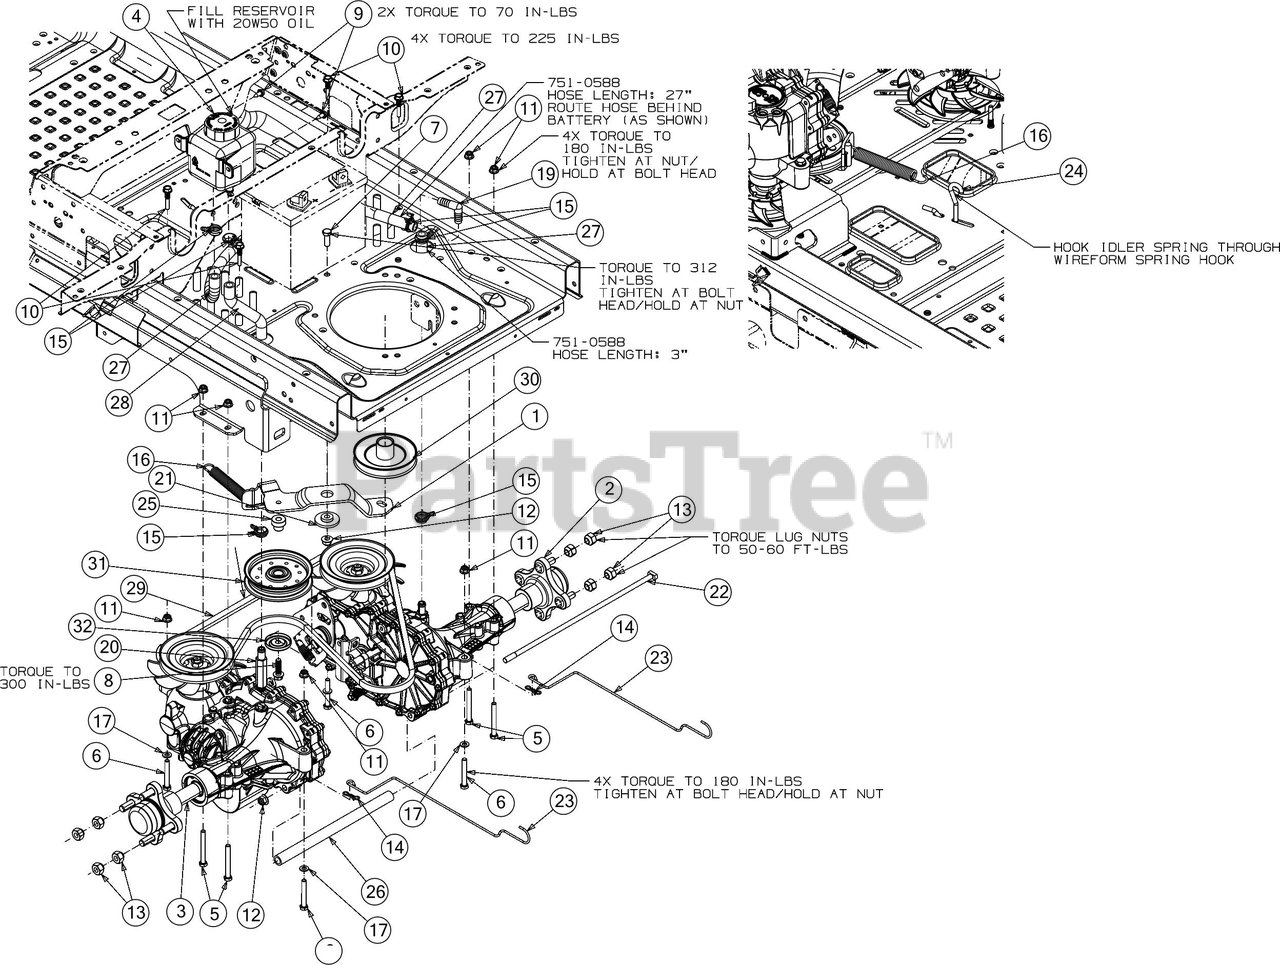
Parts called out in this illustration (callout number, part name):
1	IDLER BRACKET ASSEMBLY
2	HYDRO TRANSMISSION ASSEMBLY (RH)
3	HYDRO TRANSMISSION ASSEMBLY (LH)
4	HYDRAULIC TANK
5	HEX SCREW 5/16-18 x 2.75
6	HEX SCREW 5/16-18 x 2.25 GR5
7	SCREW 3/8-16 x 1 GR5
8	SCREW 3/8-16 X1.250
9	SCREW 1/4-20X.625
10	BELT KEEPER ROD .25 x 1.585
11	FLANGE LOCK NUT 5/16-18
13	LUG NUT 7/16-14
14	BOW TIE COTTER PIN 1/4-5/16
15	FUEL HOSE CLAMP
16	EXTENSION SPRING .75 DIA x 5.87 RZT/F
17	FLAT WASHER
19	90 DEGREE NYLON FITTING
20	EXTENSION FITTING 9/16-18
21	SHOULDER SPACER
22	SUPPORT TUBE ROD
23	HYDRO BYPASS ROD
24	IDLER SPRING HOOK
25	SHOULDER SPACER
26	TRANSMISSION SPACER .75OD x 11.31
27	FUEL LINE 1/2 ID"
28	TRANSMISSION EXPANSION HOSE
29	TRANSMISSION DRIVE BELT A x 67
30	TRANSMISSION PULLEY
31	IDLER PULLEY 4.25 DIA
32	IDLER PULLEY CAP
